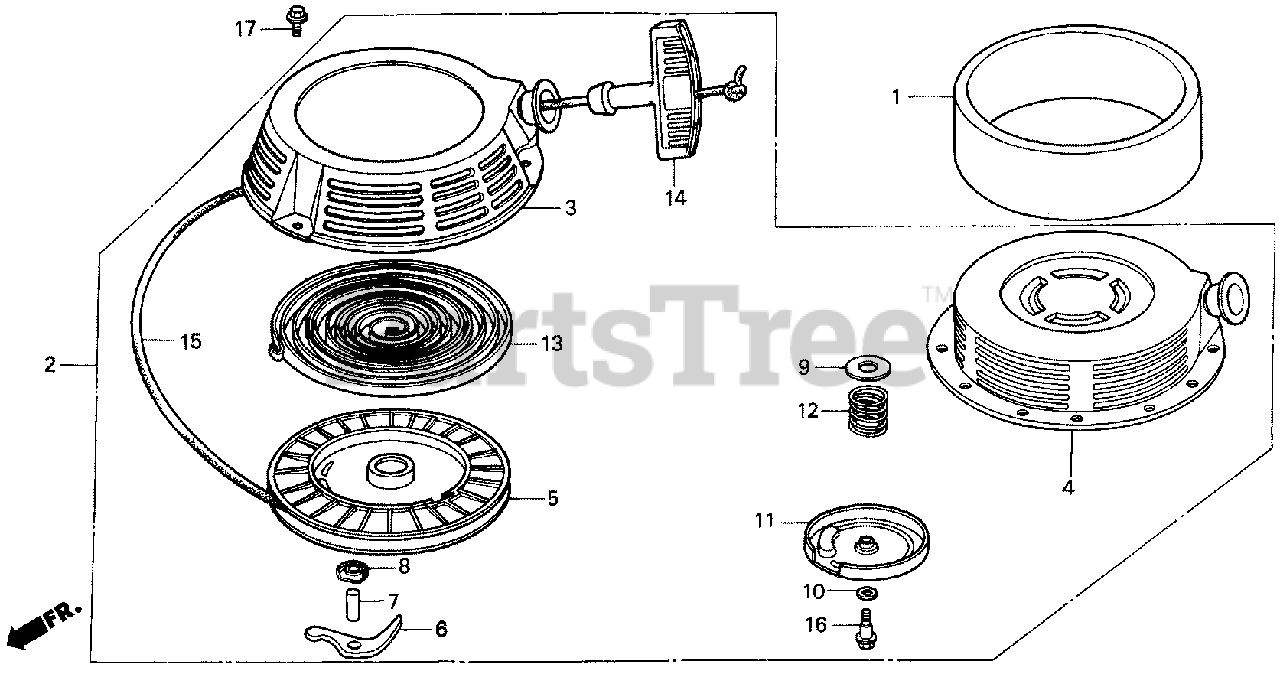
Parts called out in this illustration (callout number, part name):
1	FILTER, AIR
2	STARTER ASSY., RECOIL *R8* (Honda Code 3417292). (BRIGHT RED)
4	CASE, RECOIL STARTER *R8* (Honda Code 3577582). (BRIGHT RED)
5	REEL, STARTER
6	RATCHET, STARTER
7	SHAFT, RATCHET
8	PLATE, GUIDE
9	PLATE A, FRICTION
10	PLATE B, FRICTION
11	COVER, REEL STARTER
12	SPRING, FRICTION
13	SPRING, RETURN
14	GRIP, STARTER
15	ROPE, STARTER (#6X64") (Honda Code 2106433). (N/A: USE ALT P/N 08560-ZG921-11)
16	BOLT, REEL COVER
17	BOLT, FLANGE (6X10) (Honda Code 2832061). (NOT AVAILABLE)
17	BOLT, FLANGE (6X8)
